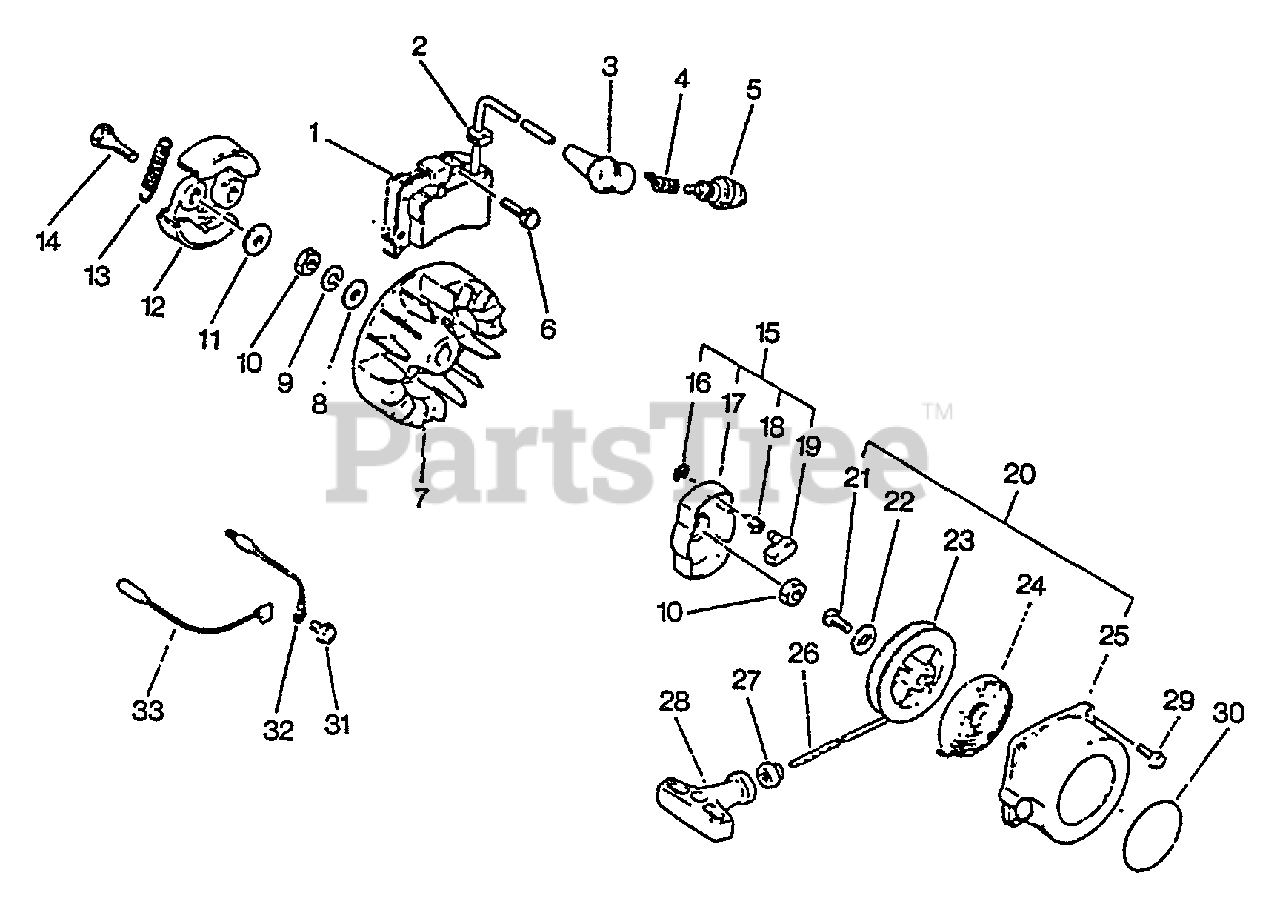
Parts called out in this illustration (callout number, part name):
1	COIL, IGNITION
3	CAP, SPARK PLUG
4	TERMINAL, SPARK PLUG CAP
5	SPARK PLUG -- BPM-7A
5	SPARK PLUG -- BPMR-7A
6	SCREW - 5X20
7	FLYWHEEL
8	WASHER - 8
9	LOCKWASHER - 8
11	WASHER - 6
12	SHOE, CLUTCH
13	SPRING, CLUTCH
14	BOLT, CLUTCH
15	STARTER PAWL ASSY
16	RING, RETAINING - 6
17	CATCHER, PAWL
18	SPRING, RETURN
19	PAWL, STARTER
20	STARTER ASSY - GRAY
22	WASHER
23	REEL, ROPE
24	SPRING, REWIND
25	CASE, STARTER
26	ROPE, STARTER - 3.5X850
27	GUIDE, ROPE
28	GRIP, STARTER
29	SCREW - 4X14
30	LABEL - ECHO
31	SCREW - 5X10
32	LEAD - GROUND
33	LEAD - GROUND
